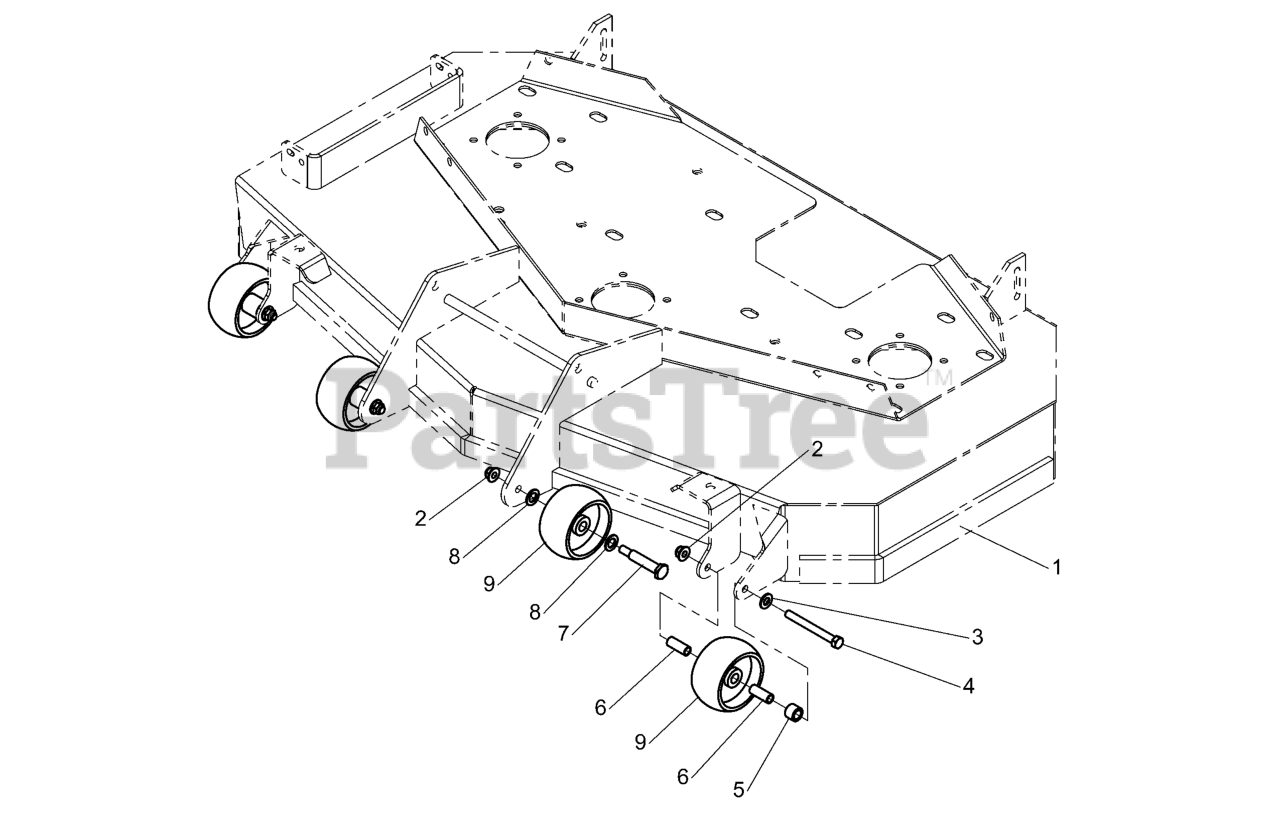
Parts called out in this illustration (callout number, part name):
1	MOWER DECK
2	NUT, 3/8-16 HEX NYLOCK FLANGE
3	WASHER, 3/8 SAE
4	BOLT, 3/8-16 X 3-1/2" GD5 CZ
5	SPACER, .51 X .75 X .56
6	SPACER, .38 X .50 X 1.25, CZ
7	BOLT, REAR WHEEL
8	WASHER,.516IDX.875ODX.06,FLAT,ZC/CL
9	WHEEL- 2.00 WIDE 3.88 DIA 0.531ID POLY
